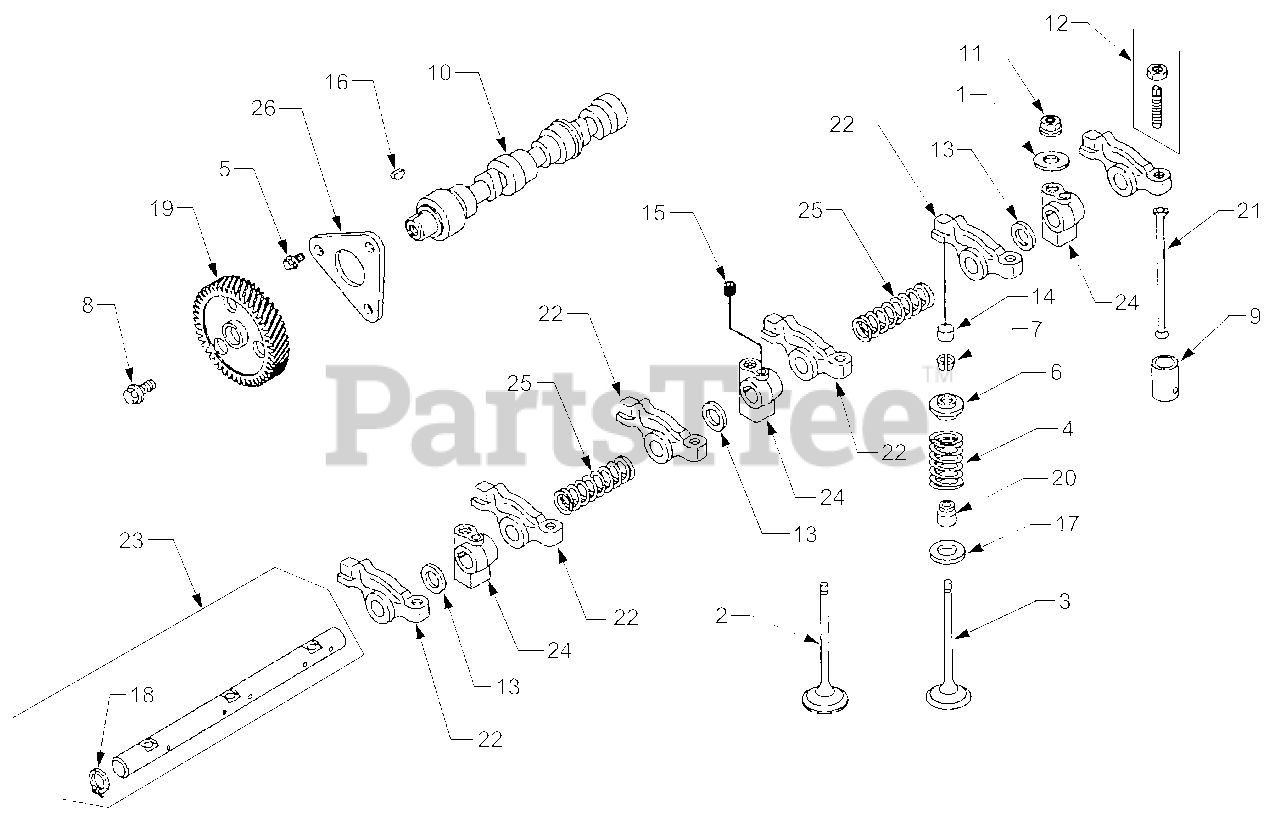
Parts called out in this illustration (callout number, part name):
1	Washer, Flat
2	Valve, Exhaust
3	Valve, Intake
4	Spring, Valve
5	Screw, Hex, 6mm
6	Retainer, Valve
7	Keeper, Valve, Set of 2
8	Screw, Metric
9	Tappet, Valve
11	Nut, Hex Metric
12	Adjuster, Rocker Arm
13	Washer, Spacer
14	Cap, Valve
15	Screw, Metric
16	Key, Timing
17	Seat, Valve Spring
20	Seal, Valve
22	Arm, Rocker
23	Shaft, Rocker Arm
24	Support, Rocker Arm
25	Spring, Rocker Shaft
26	Retainer, Camshaft
